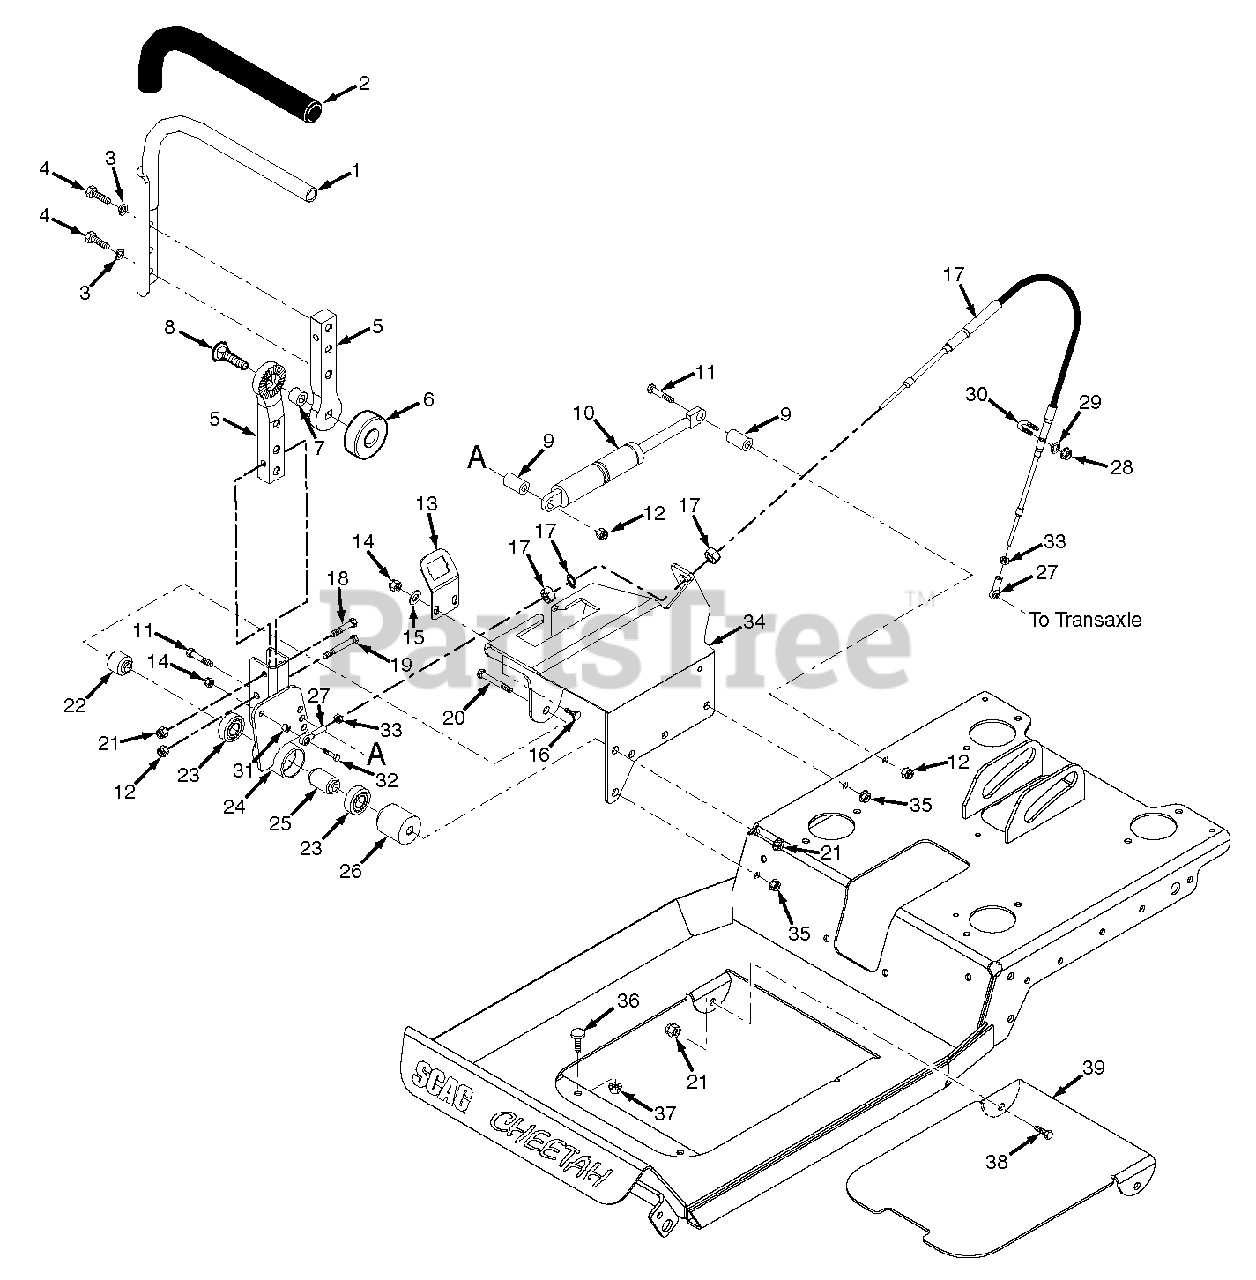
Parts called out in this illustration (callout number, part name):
1	Handle Bar w/Grip, LH
1	Handle Bar w/Grip, RH
2	Grip, Control Handle
3	Lockwasher, 5/16-" Spring'
4	Bolt, Hex Head 5/16-18 x 1'
5	Pivot, Control Lever
6	Knob, Control Handle
7	Spacer, Rubber
8	Bolt, Carriage 3/8-16 x 1-1/2"
9	Spacer
10	Damper
11	Bolt, Hex Head 5/16-18 x 2"
12	Nut, Elastic Stop 5/16-18
13	Bracket, Operator Presence Switch
14	Nut, Elastic Stop 1/4-20
15	Flatwasher, 1/4-.312 x .750 x .065
16	Bolt, Carriage 1/4-20 x 3/4"
17	Control Cable, Hydro
18	Bolt, Hex Head 3/8-16 x 2"
19	Bolt, Hex Head 5/16-18 x 2"
20	Bolt, Hex Head 3/8-16 x 6"
21	Nut, Elastic Stop 3/8-16
22	Spacer, Controls
23	Bearing
24	Pivot Weldment, Control Arm LH
24	Pivot Weldment, Control Arm RH
25	Spacer, Bearing
26	Spacer, Controls
27	Rod End, 1/4-28 RH Thread
28	Nut, Jam 5/16-24 UNF-2B
29	Lockwasher, 5/16" Spring
30	U-Bolt, 5/16-24
31	Spacer
32	Bolt, Hex Head 1/4-20 x 1-1/4"
33	Nut, Jam 1/4-28 UNF
34	Bracket Weldment, Control Lever RH w/Decal
34	Bracket Weldment, Control Lever LH w/Decal
35	Nut, Serrated Flange 3/8-16
36	Bumper, Rubber
37	Nut, Serrated Flange 5/16-18
38	Bolt, Hex Head 3/8-16 x 1"
39	Cover, Footplate
